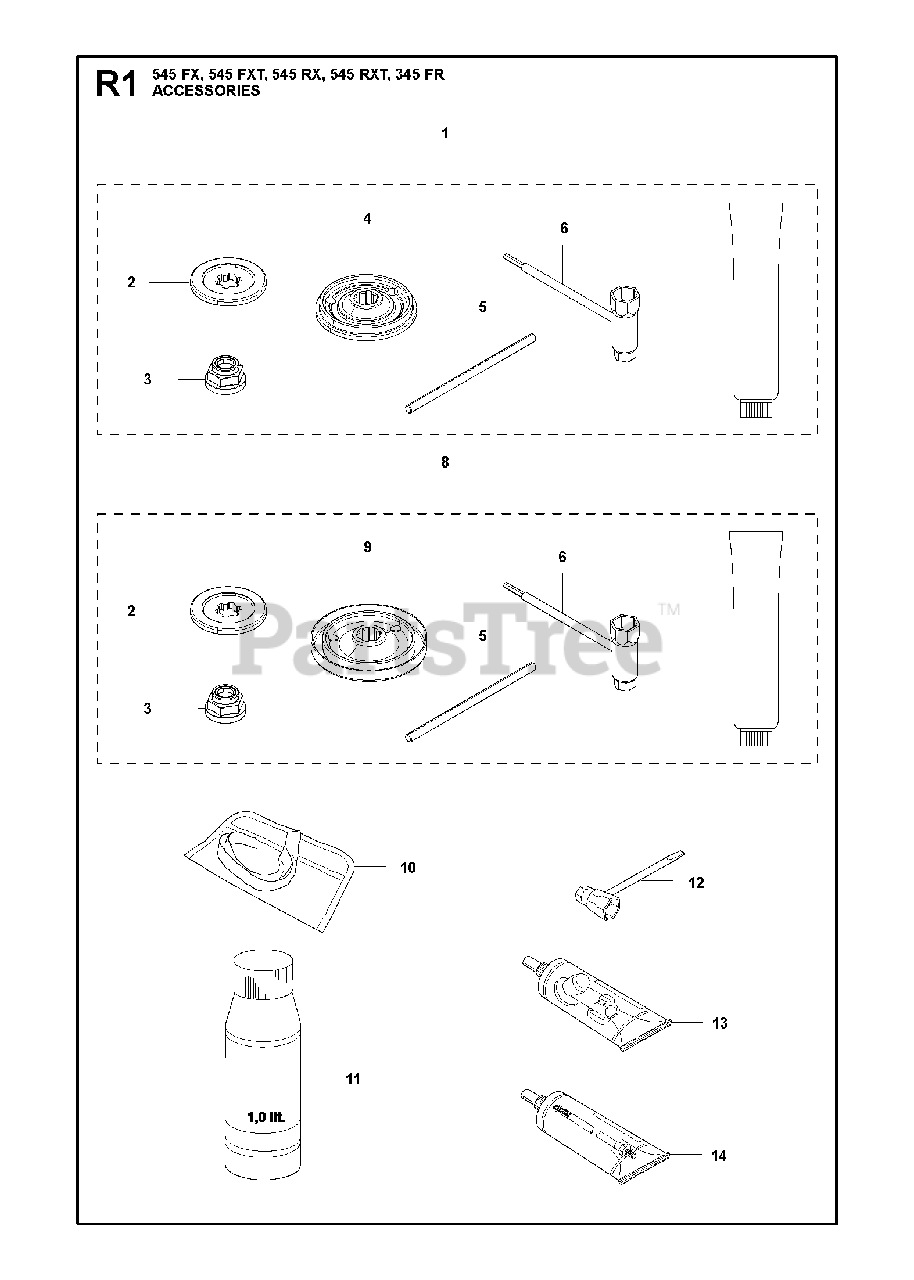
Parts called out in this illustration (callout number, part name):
1	ACCESSORY BAG
2	FLANGE
3	NUT BLADE
4	DRIVER
5	LOCKING PIN
6	COMBINATION WRENCH
8	ACCESSORY BAG
9	CARRIER
11	Air Filter Oil, HVA 1L Bottle
12	RP COMBI TOOL
13	BEVEL GEAR GREASE
